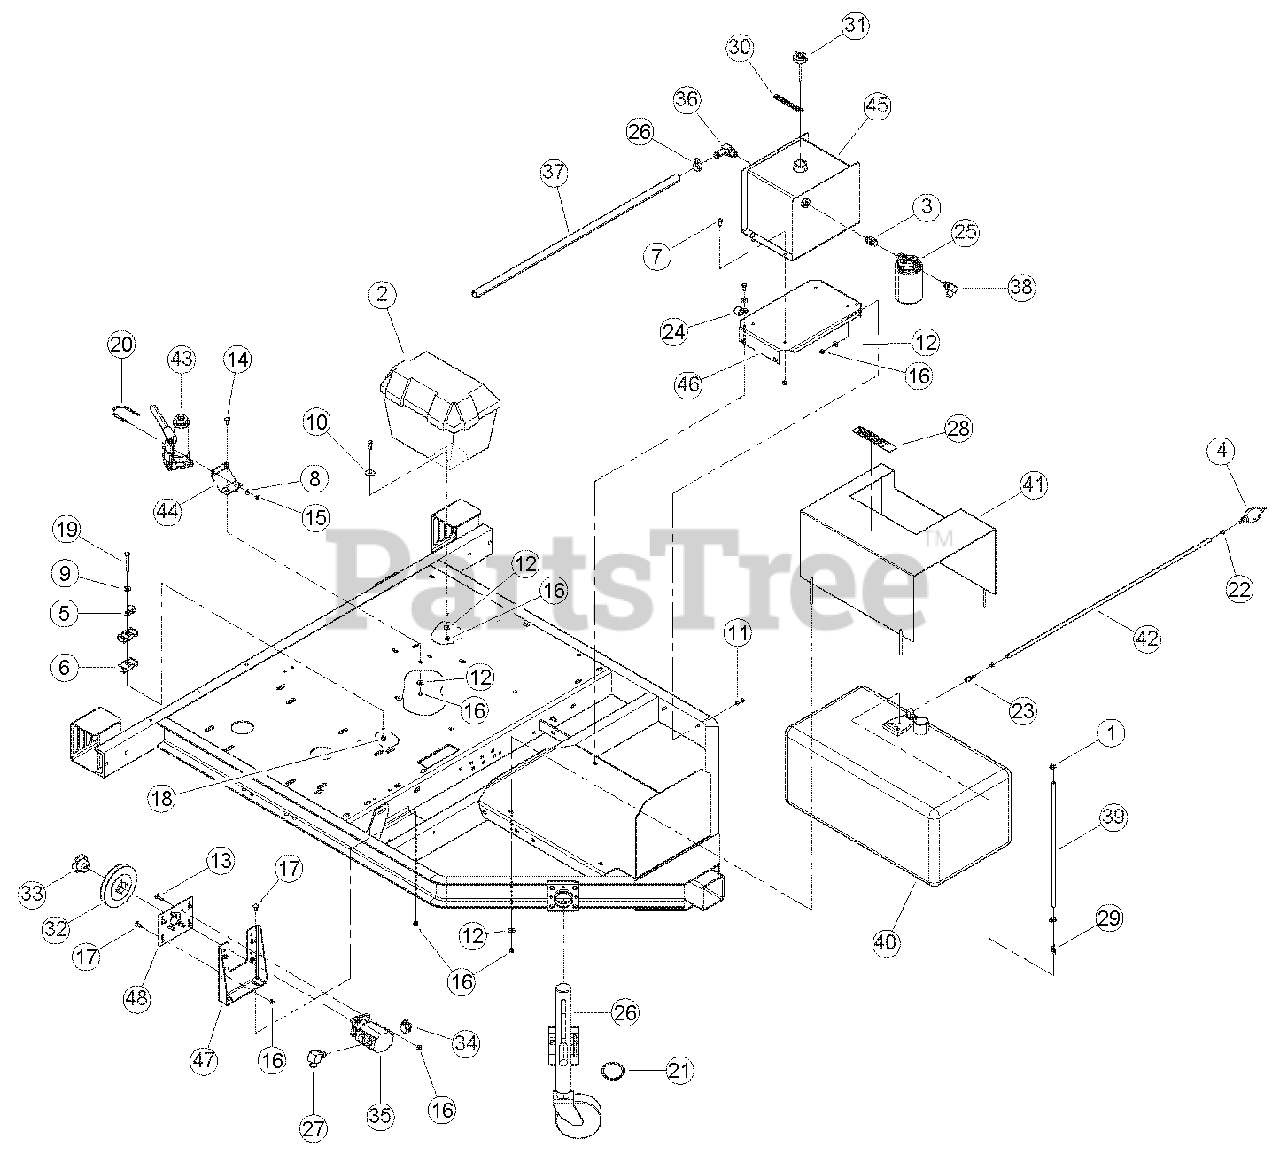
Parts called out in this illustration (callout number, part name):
1	CLAMP, HOSE 5/16 X 5/8 DIA. MAX.
2	BOX, PLASTIC BATTERY-11" X 7 1/2" X 8 3/4" [VIN: 5VJAA0016AW002226 - 5VJAA001XAW002463] [SUPERSEDED BY 12271]
2	BOX, PLASTIC BATTERY-14 13/16" X 9 5/8" X 10 5/8"
3	ADAPTER, -8 MORING / -8 MJIC
4	BULB, PRIMER
5	CLAMP, 9/16 COATED
6	CLAMP, PLASTIC OSE
7	BOLT, 5/16 X 3/4 HEX HD GR5 ZP
8	WASHER, 1/4 FLAT ZP
9	WASHER, 3/8 FLAT ZP
10	WASHER, 5/16 FENDER ZP
11	BOLT, 5/16 X 1 HHCS GR5 NC ZP
12	WASHER, 5/16 FLAT ZP
13	BOLT, 5/16 X 1 CRG GR5 ZP
14	BOLT, 5/16 X 7/98CRG GR5 NC ZP
15	NUT, 1/4 NE NYLOCK ZP
16	NUT, 5/16 NE NYLOCK ZP
17	BOLT, 5/16 X 3/4 CRG GR5 NC ZP
18	NUT, 3/8 NE NYLOCK ZP
19	BOLT, 3/8 X 2-3/4 HHCS GR5 NC ZP
20	U-BOLT, 1/4 X 1-1/2 PIPE
21	CLAMP, 15/32 SPRING
22	FITTING, 1/4 NPT. X 1/4 HOSE
23	CLAMP, 1 IN. COATED METAL
24	FILTER, SPIN-ON
25	CLAMP, 1-1/4 HOSE
26	JACK, PIVOTING W/SWIVEL CASTOR
27	ADAPTER, -10 MORING / -10 MJIC 90 DEG.
28	DECAL, DIESEL FUEL
29	FITTING, 1/8 MNPT X 1/4 HOSE
30	DECAL, HYDRAULIC FLUID
31	CAP, W/DIPSTICK
32	SHEAVE, QT 1B5.6
33	BUSHING, QT 1/2
34	PUMP, PB CW HI/LO .646 DISP.
35	ADAPTER, -10 MORING / .75 90 DEG. HOSE
36	HOSE, .75 ID. X 38 IN. 100R4 HYD.
37	ADAPTER, -8 MORING / -8 MJIC 90 DEG.
38	WELDMENT, CHIPPER TRAILER
39	HOSE, 76 IN. FUEL RETURN
40	TANK, DIESEL FUEL
41	WELDMENT, FUEL TANK CLAMP
42	HOSE, 38 IN. FUEL LINE
43	JACK, HYDRAULIC 2 TON
44	PLATE, JACK MOUNT
46	SHEET, TANK MOUNT
47	BRACKET, MOUNT HYDRAULIC PUMP
48	PLATE, MOUNT HYDRAULIC PUMP
